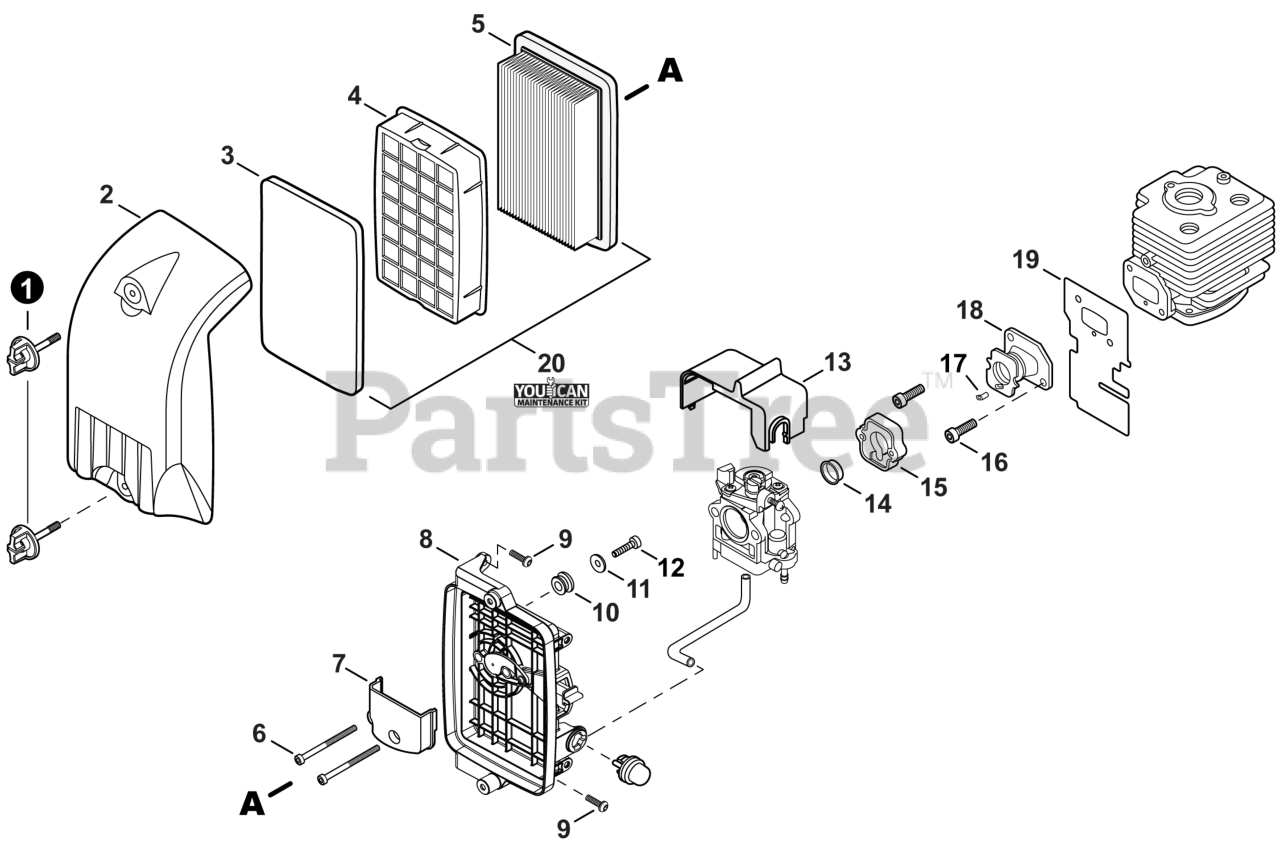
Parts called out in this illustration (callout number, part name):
1	THUMBSCREW
2	COVER, AIR FILTER
3	PRE-FILTER, FOAM
4	RETAINER, PRE-FILTER
5	FILTER, AIR
6	BOLT, TORX 5x55
7	PLATE, PREVENT
8	CASE, AIR FILTER
9	BOLT, TORX 5x20
10	GUIDE, CABLE
11	WASHER 5.5x16x0.8
12	BOLT, TORX 5x16
13	CAP, CARBURETOR
14	RING, SEAL
15	ADAPTOR, INTAKE
16	SCREW 5x12
17	COLLAR 3
18	BELLOWS, INTAKE
19	HEAT SHIELD, INTAKE
20	TUNE-UP KIT - YOUCANT
